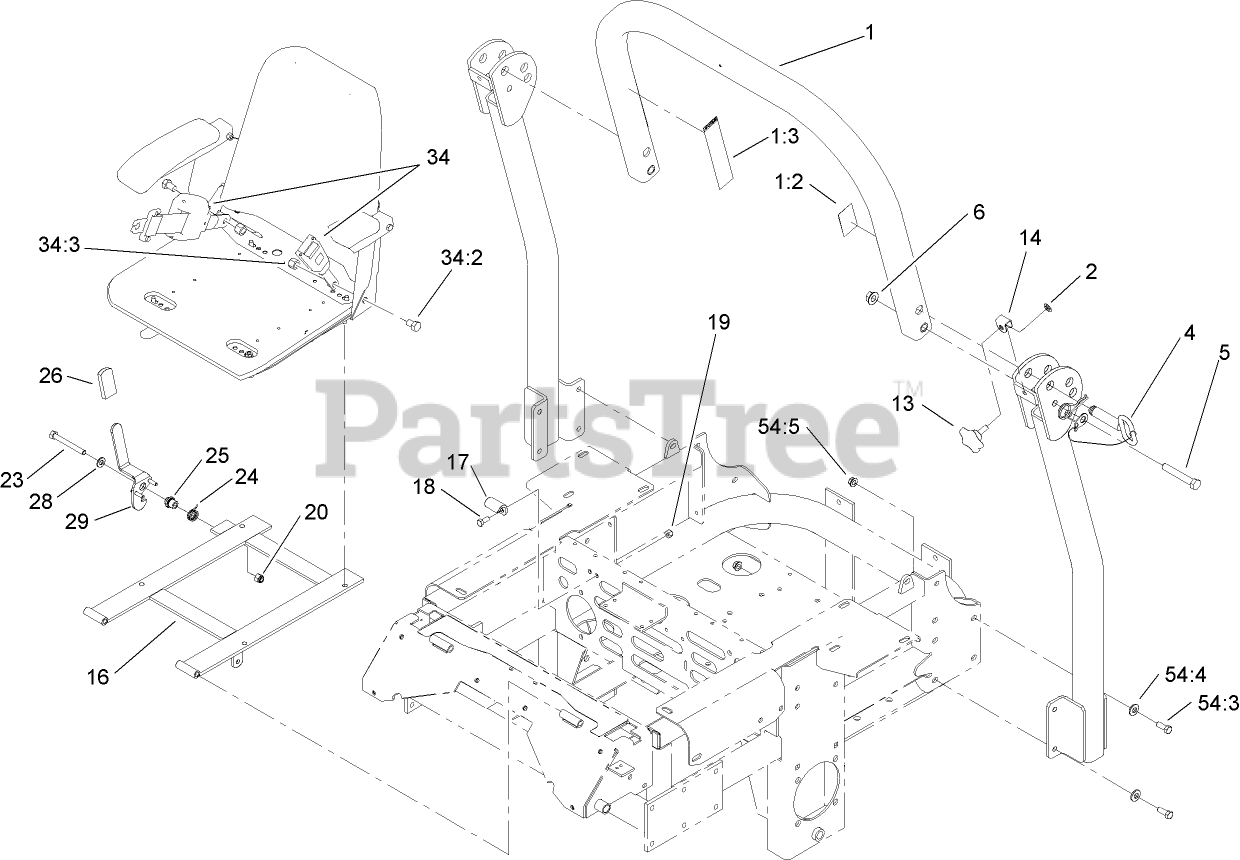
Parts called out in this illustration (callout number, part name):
1	Upper Tube ASM
1:2	DECAL-ROPS
1:3	DECAL-WARNING, FOLDING ROPS
2	NUT-PUSH
4	PIN-FOLD, ROPS
5	SCREW-HH
6	NUT-HF
16	SEAT SUPPORT FRAME ASM
17	Catch-Latch, Seat
18	SCREW-HH
19	NUT-LOCK, NI
20	NUT-LOCK, NI
23	SCREW-HH
24	SPRING-TORSION
25	BUSHING-LATCH, SEAT
26	GRIP-LEVER
28	WASHER-FLAT
29	LATCH ASM
34	RETRACTABLE SEATBELT KIT
34:2	SCREW-HH
34:3	NUT-LOCK
54:3	SCREW-HH
54:4	WASHER-BELLEVILLE
54:5	NUT-HHF, WHIZ
